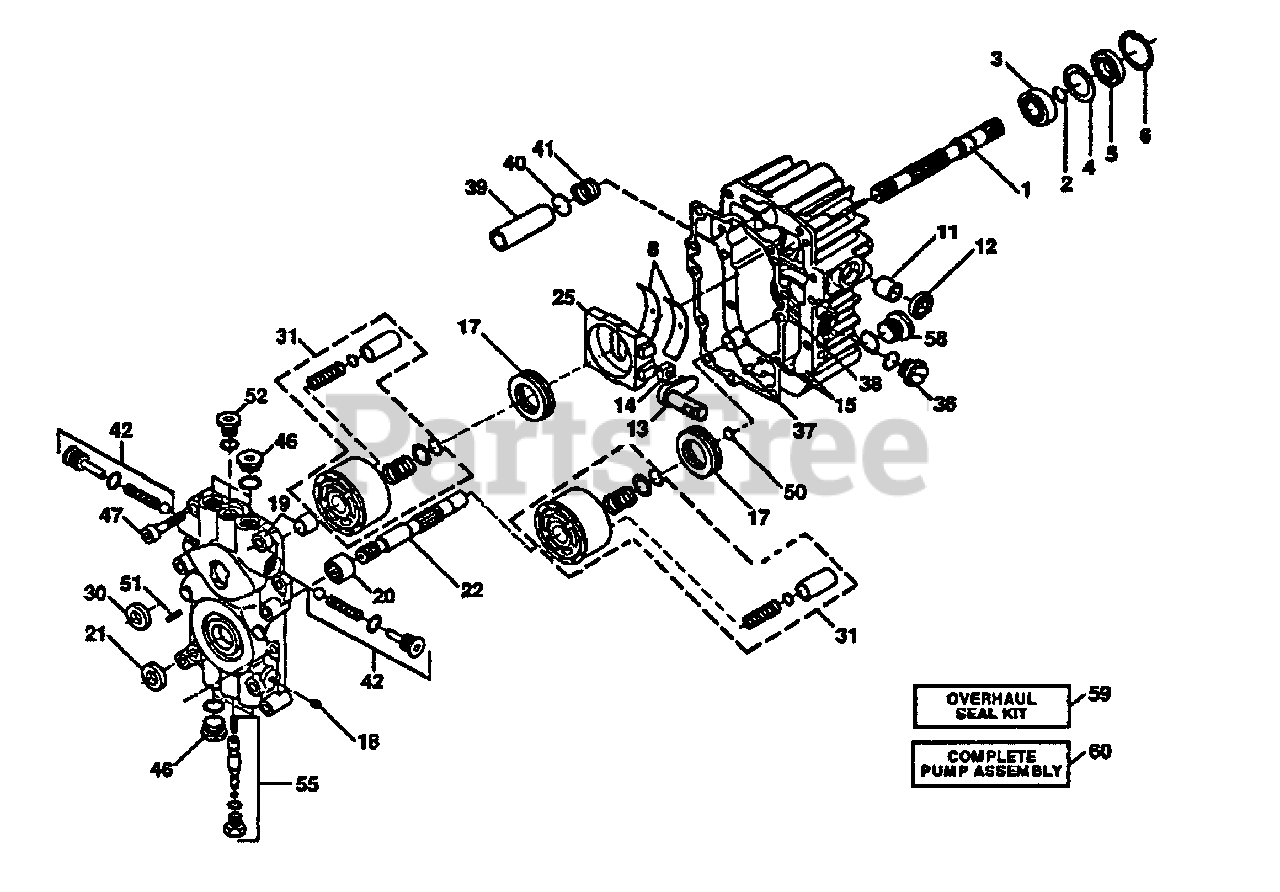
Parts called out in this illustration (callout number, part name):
1	Shaft, Pump
2	Ring, Retaining
3	Bearing, Ball
4	Spacer
5	Seal, up
6	Rlng, Retaining
8	Bearing, Cradle
11	Bearing, Journal
12	Seal, Up
13	Arm, Trunnion
14	Guide, Slot
15	Housing Kit, Transmission
17	Bearing, Thrust, Ball
18	Plug, Pipe
19	Center Section Kit
20	Bearing, Needle
21	Seal, up
22	Shaft, Motor
25	Swashplate, Variable
30	Seal, Lip
31	Block Kit, Cylinder
36	Plug, Plastic
37	Pin, Stainless, Headless
38	Gasket, Center Section
40	Washer Thrust
41	Spring, Helical, Compression
42	Check Valve Kit
46	Plug, Stainless, Threaded
47	Screw, Socket Head, Cap
50	Washer, Thrust
51	Pin, Spiral
52	Plug, Stainless, Threaded
55	Bypass Valve Kit
58	Plug, Stainless, Threaded
59	Overhaul Seal Kit, BDU-10
60	Pump Assembly, Complete
